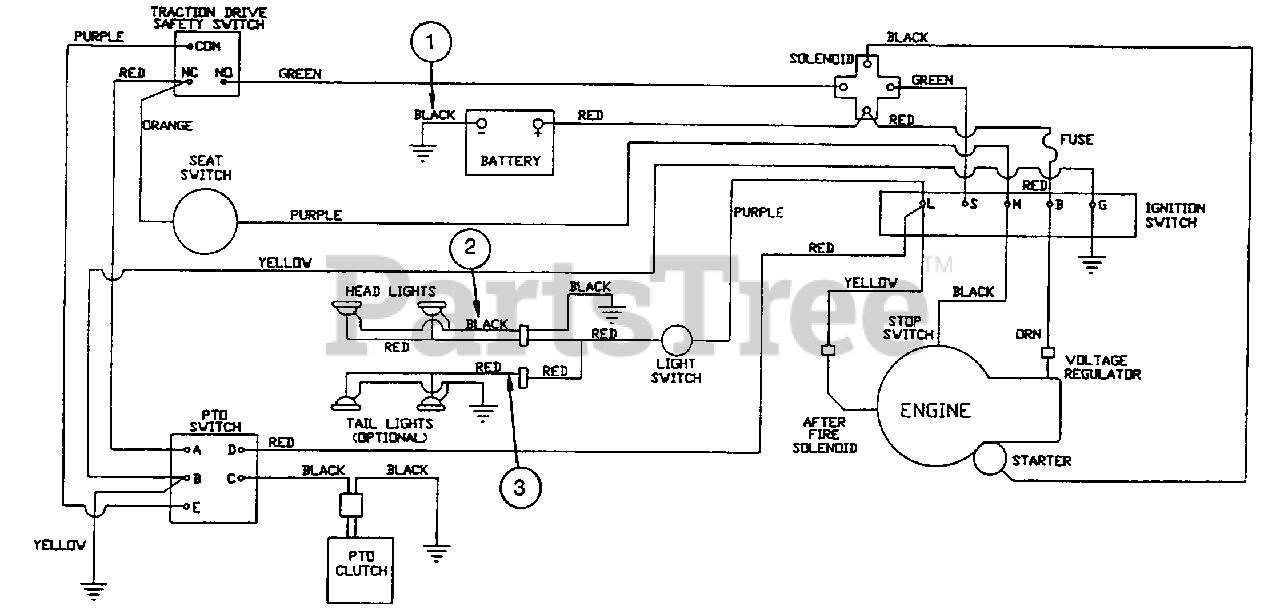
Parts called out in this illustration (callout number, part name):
1	CABLE- Battery (-) Black
2	HARNESS- Headlights
3	HARNESS- Taillights
